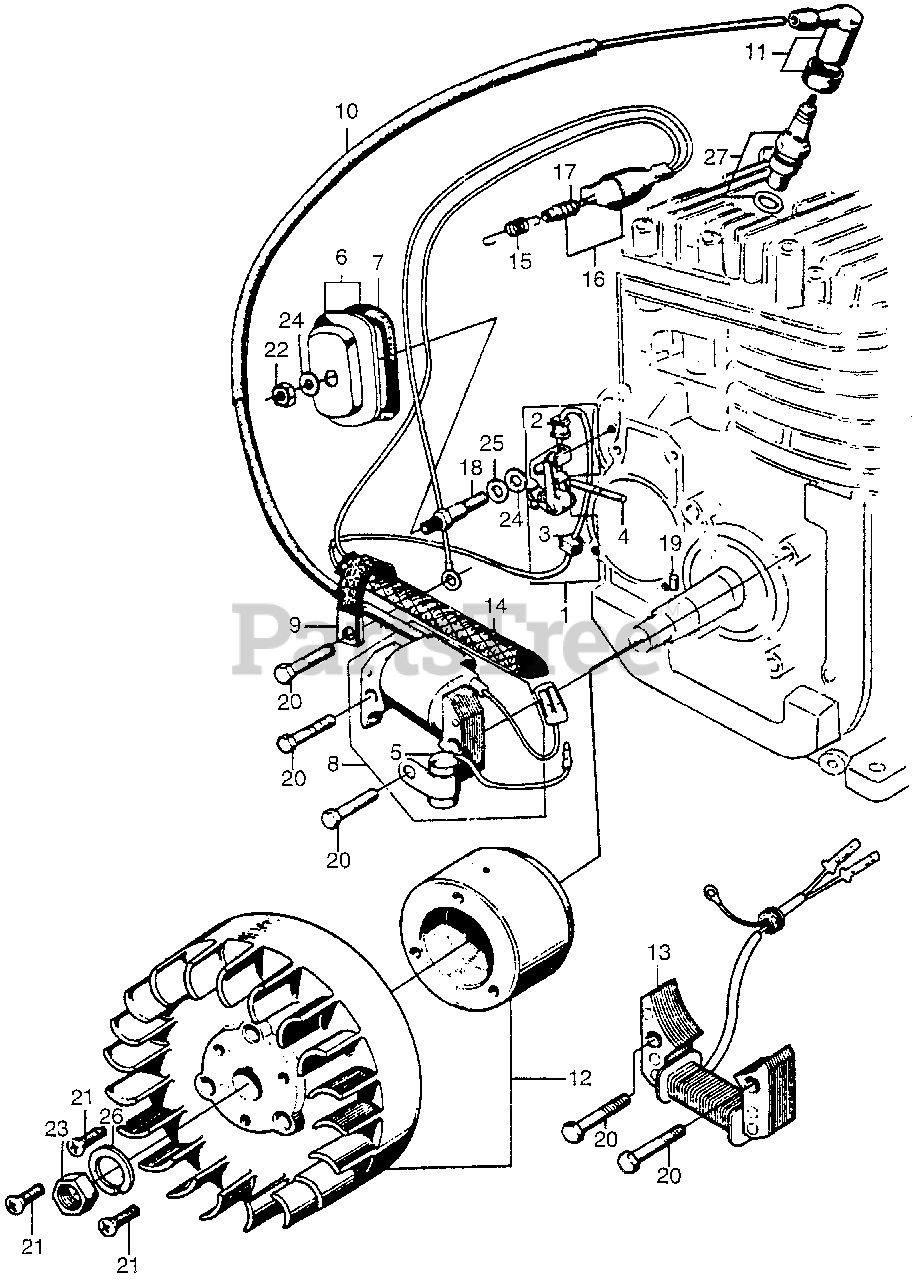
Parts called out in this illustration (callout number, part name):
1	POINTS (N/A: SEE ASSEMBLY)
1	POINTS
4	ROD, POINT PUSH
5	CONDENSER (NOT AVAILABLE)
6	COVER, POINTS (NOT AVAILABLE)
7	GASKET, POINTS COVER
8	COIL, IGNITION
9	CLAMP, WIRE
10	TUBE, IGNITION RUBBER
11	TERMINAL ASSY., IGNITION
12	FLYWHEEL
12	FLYWHEEL (NOT AVAILABLE)
12	FLYWHEEL (OPTIONAL 4 POLE MAG)
13	COIL, OUTPUT (6.4V/17W) (NOT AVAILABLE)
14	TUBE, LEAD CABLE
15	SPRING, SWITCH
16	SWITCH, ENGINE STOP (NOT AVAILABLE)
17	BOOT, ENGINE STOP SWITCH
18	BOLT, POINTS SETTING
19	ROLLER (5X6)
20	BOLT, HEX. (6X32)
21	SCREW, FLAT (6X22) (NOT AVAILABLE)
22	NUT, HEX. (6MM)
23	NUT, HEX. (16MM) (NOT AVAILABLE)
24	WASHER, PLAIN (6MM)
25	WASHER, SPRING (6MM)
26	WASHER, SPRING (16MM)
27	SPARK PLUG (B-4H)
